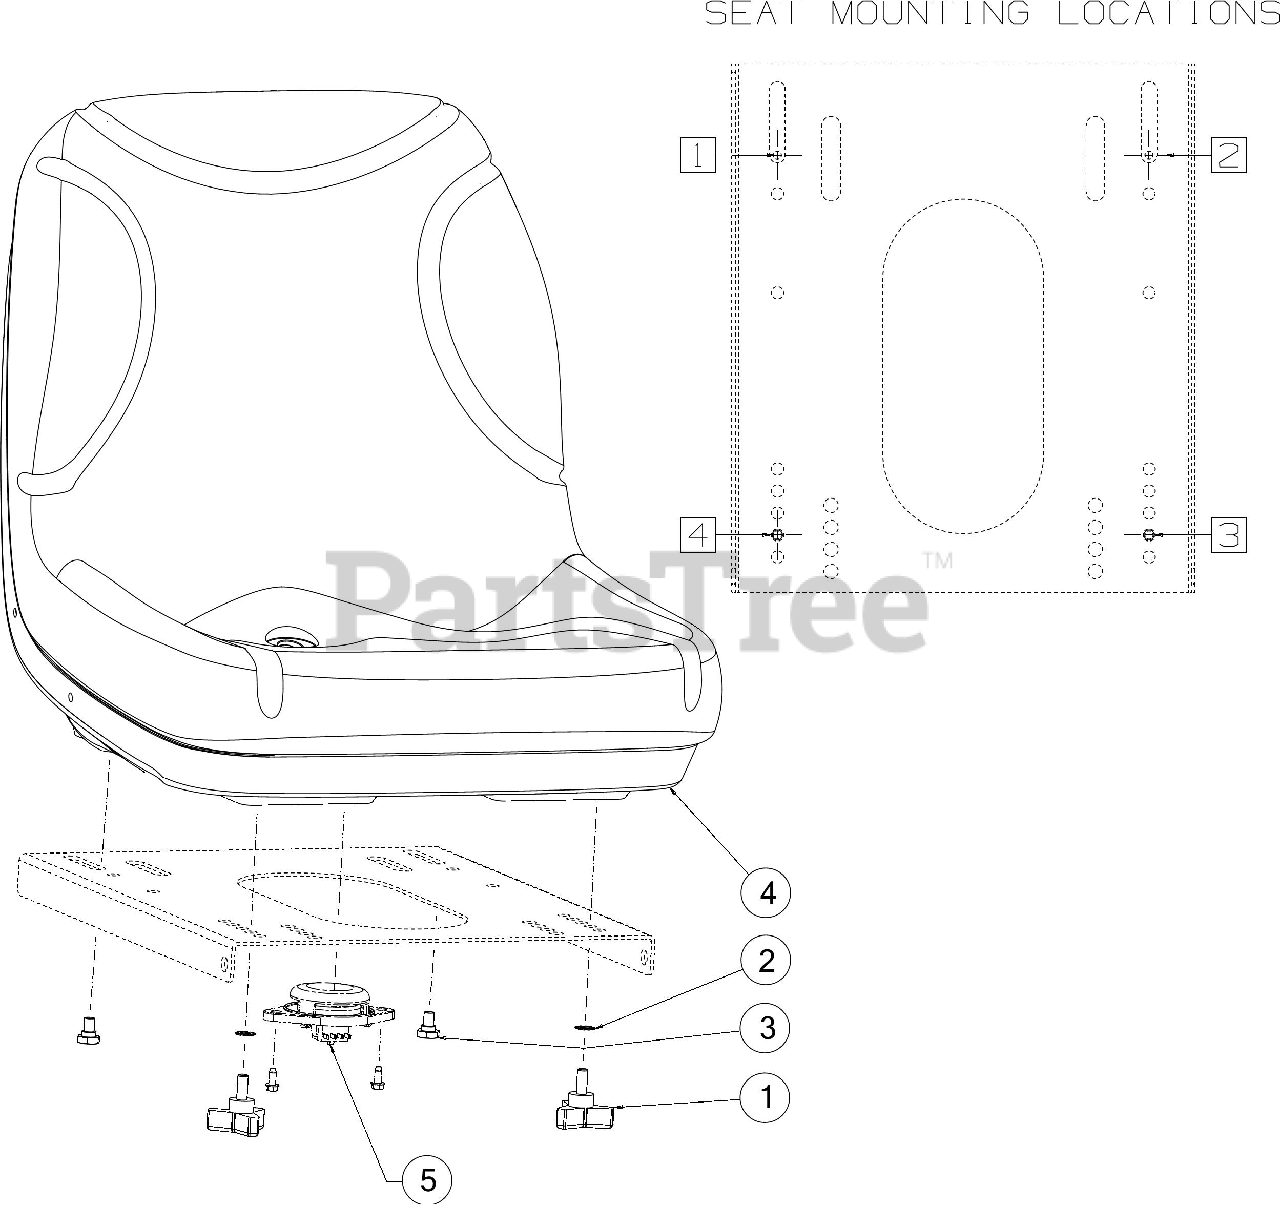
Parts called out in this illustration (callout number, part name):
1	THREE ARM KNOB
3	SHOULDER SCREW .437
4	19" SEAT 4-PT MOUNT
5	SEAT SWITCH NC/NC
